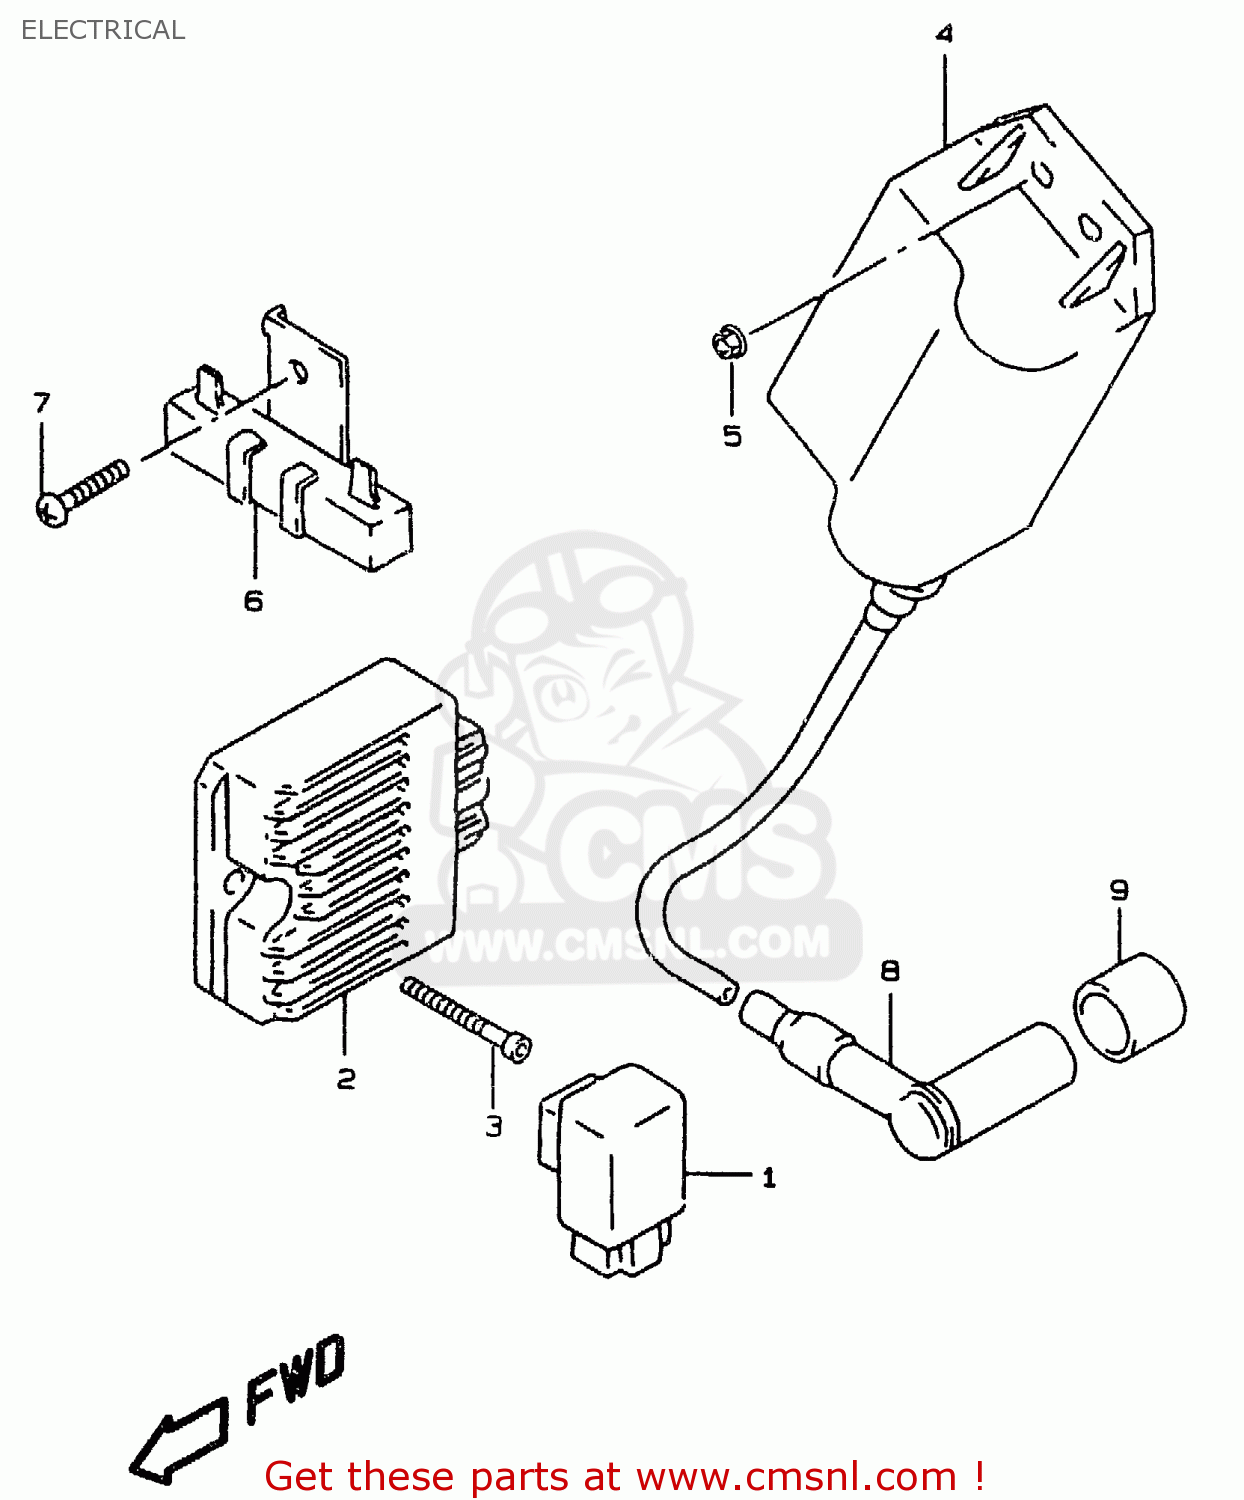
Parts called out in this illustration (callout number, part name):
1	RELAY ASSY,STARTING MOTOR
2	RECTIFIER ASSY
3	BOLT,OIL FILLE
4	UNIT&COIL,IGNI
5	NUT
6	RESISTOR ASSY
7	SCREW
8	CAP ASSY, SPAR
9	BOOT,SPARK PLU
